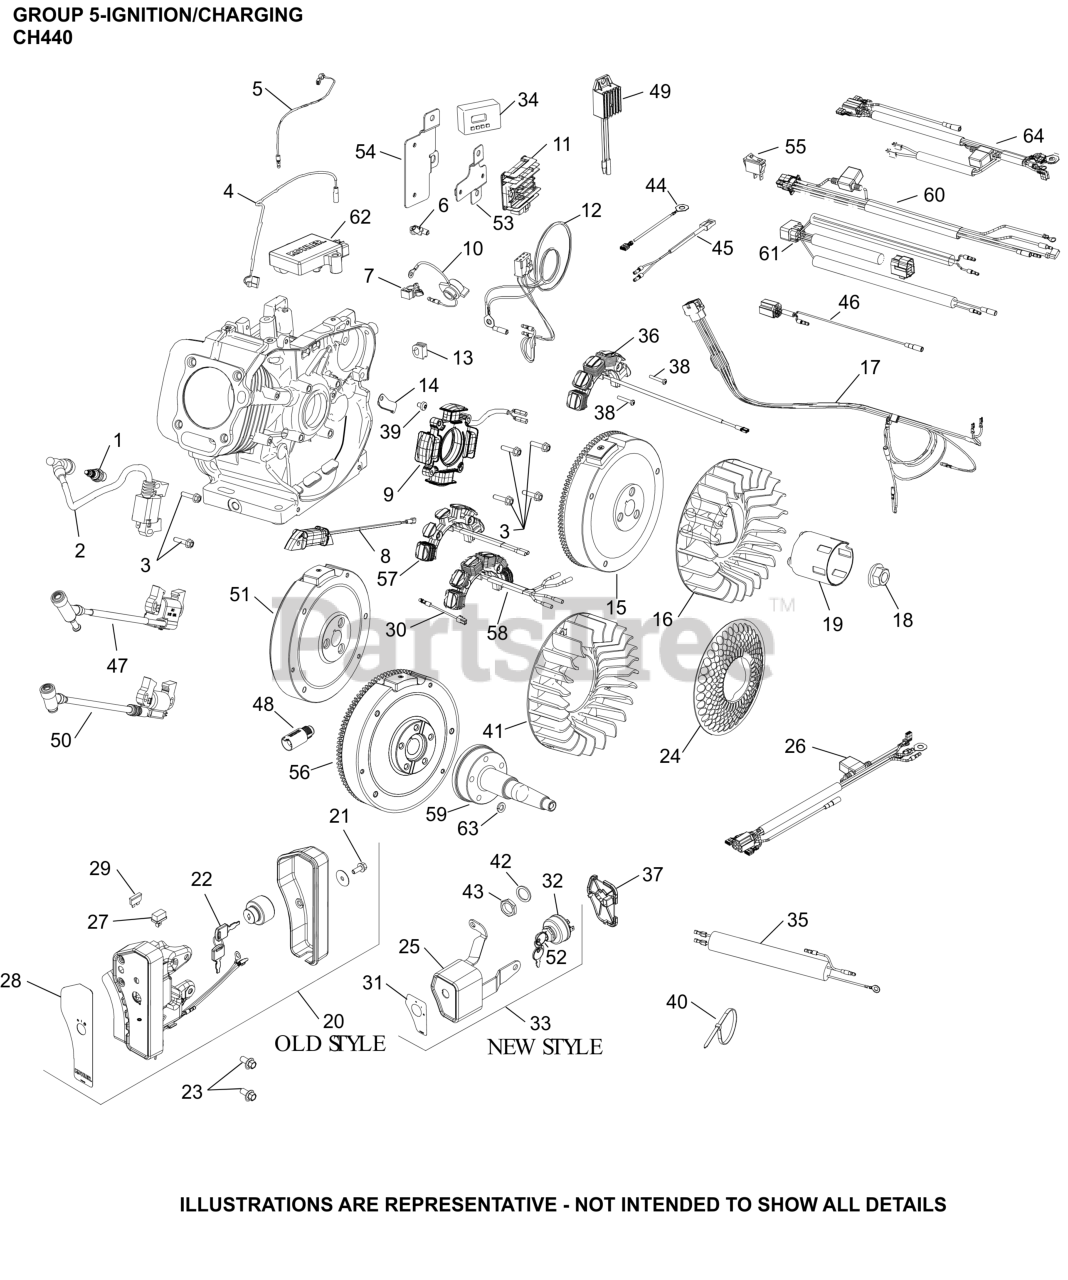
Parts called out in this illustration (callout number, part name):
1	SPARK PLUG
2	MODULE, IGNITION
3	SCREW, M6 X 25-(#25086436S)
4	LEAD, GROUND TO KILL
14	BRACKET, STATOR WIRE
15	FLYWHEEL ASSY ELECTRIC START (CH440)
16	FAN, FLYWHEEL
18	NUT, FLYWHEEL
19	CUP, STARTER DRIVE
20	HOUSING, 3A KEY BOX ASSY-(#1775566S)
22	KEYS FOR SWITCH
25	KEYBOX HOUSING ASSEMBLY
26	HARNESS, WIRING ASSY (3 AMP)-DISC.
26	HARNESS, WIRING ASSEMBLY (3 AMP)
27	RECTIFIER
28	LABEL, ELECTRIC BOX
29	FUSE, ELECTRIC START 15 AMP
31	LABEL, KEY BOX
32	SWITCH, KEY ASSEMBLY
33	KIT, KEY BOX ASSEMBLY
33	KIT, KEY BOX CONVERSION CH440 3 AMP
36	STATOR ASSEMBLY, 3A
37	COVER, KEY BOX
38	SCREW, STATOR MOUNTING
39	SCREW, COIL BRACKET
52	KIT, KEY PLASTIC HANDLE (2 PC)
